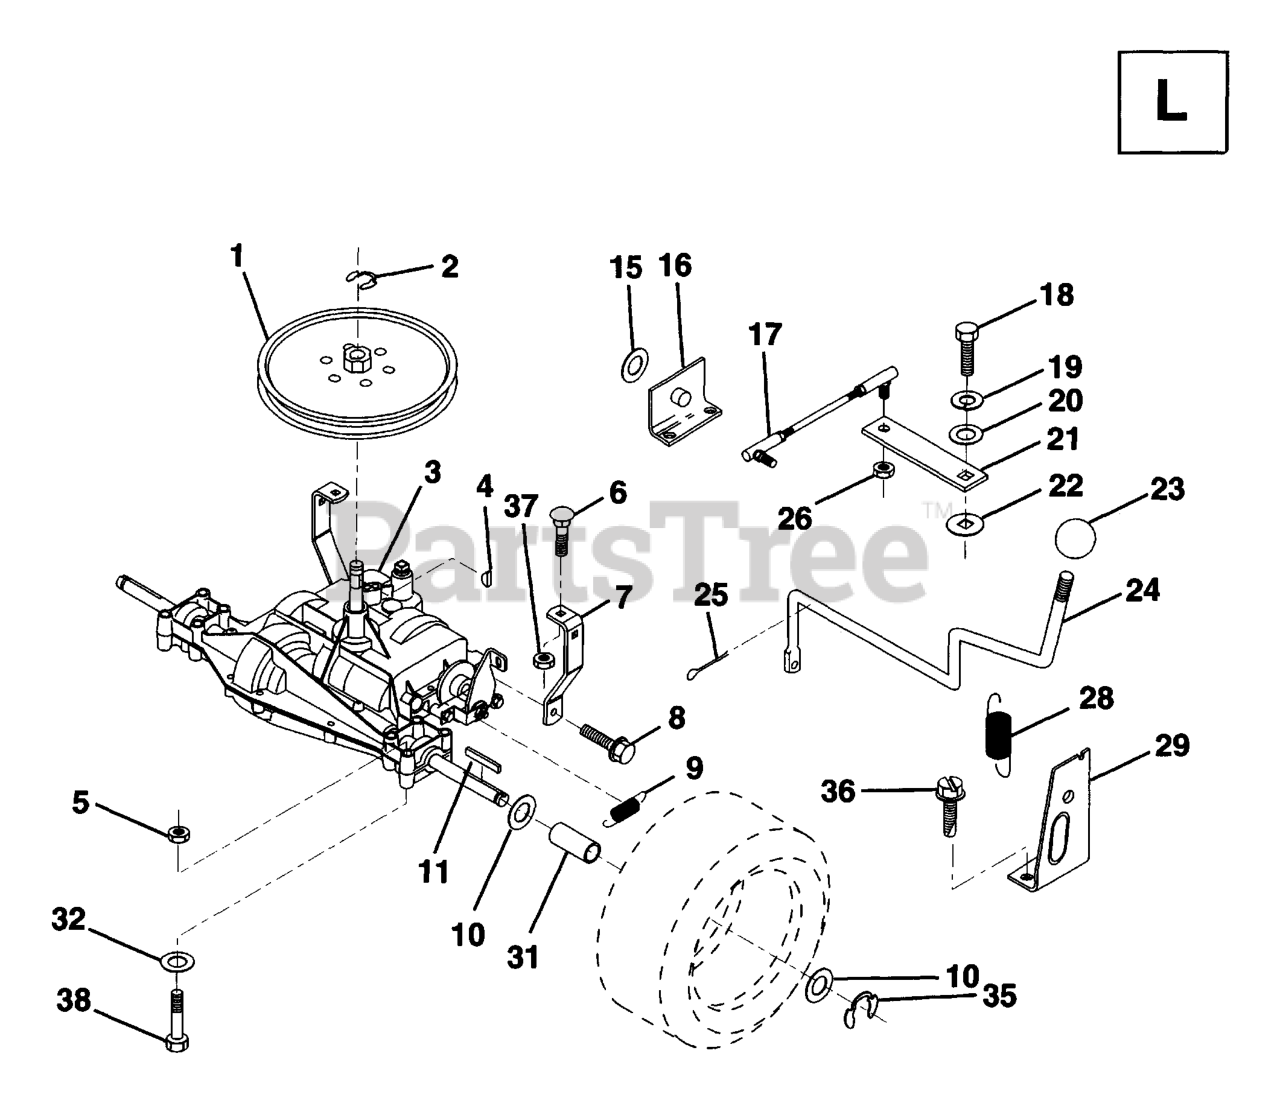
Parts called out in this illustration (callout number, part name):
2	RETAINING RING LT
4	KEY STD (1373) DANA
5	NUT.71038.31-18.HEX.NYLOCK
6	RP BOLT 5/16-18 X3/4 ZN/YEL GR
7	STRAP,TORQUE
8	SCREW.THDROL.5/16-18X3/4.TTY
9	SPRING T
11	SQUARE KEY
12	Bolt, Hex, Fin. 5/16 x 18 UNC x 2-1/2
15	WASHER
16	SUPT, HDLE SHT LH
19	LOCKWASHER
22	WASH-SHFT PLT LT
23	KNOB.DUCKHEAD.1/2
24	ROD, SHIFT
25	PIN COTTER
26	LOCKNUT
28	SPRING.EXTENSION
29	SUPPORT HANDLE SHAFT RH
31	SPACER AXLE
32	WASHER
36	BOLT
37	LOCKNUT
